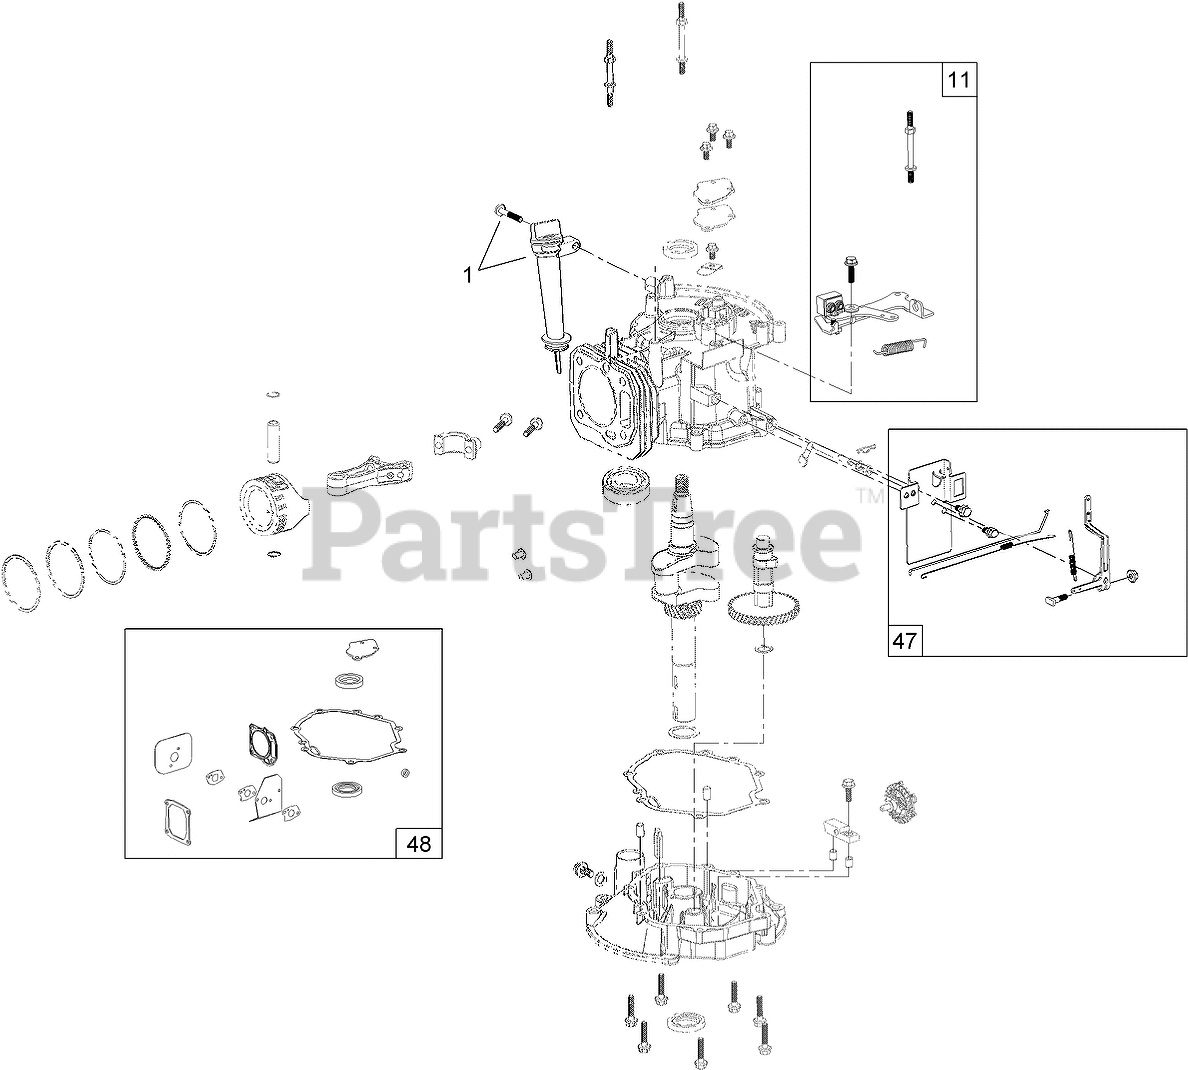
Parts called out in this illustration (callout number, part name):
1	DIPSTICK AND FILL TUBE KIT
11	BRAKE ASM RECOIL KIT
47	GOVERNOR ARM KIT
48	SEAL AND GASKET KIT
